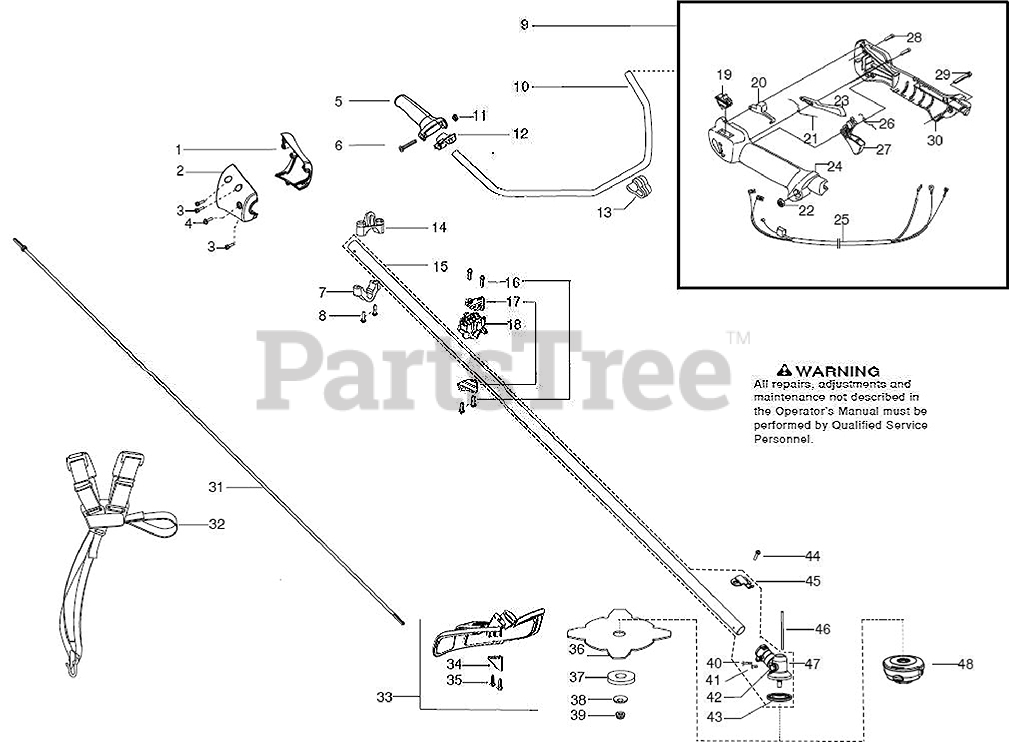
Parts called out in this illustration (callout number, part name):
1	NOSE CONE B/H LH HVA 25.4MM
7	CLAMP HARNESS LOWER
9	ASSY THROTTLE HSG
10	HANDLE BAR
14	CLAMP HARNESS UPPER
15	KIT DRIVESHAFT SS BLADE
16	SCREW 10-14X3/4 PLASTITE
17	CLAMP BRACKET
19	STOP BUTTON
20	STARTER THROTTLE LOCK
23	THROTTLE LOCKOUT
24	HANDLE HALF LEFT
25	CABLE ASSY
27	THROTTLE CONTROL
29	SCREW
31	FLEXSHAFT 57"
32	HARNESS DUO
33	KIT STRAIGHT SHIELD
34	Limiter - Line
35	SCREW 10-14X3/4 PLASTITE
36	Blade - Grass
37	SUPPORTING CUP
38	SUPPORT FLANGE
39	GEARHEAD NUT - BRUSHCUTTER
40	SCREW 8-32 X 16.51
41	SCREW 8-32 X 16.51 TT SC TRX
42	PLUG GREASE 9MM
43	DRIVE DISC
44	SCREW 1/4-20
45	BRACKET SHIELD STRAIGHT SHAFT
46	LOCKING PIN
47	ASSY GEARBOX
48	T25 TRIM HEAD 10MM LH
